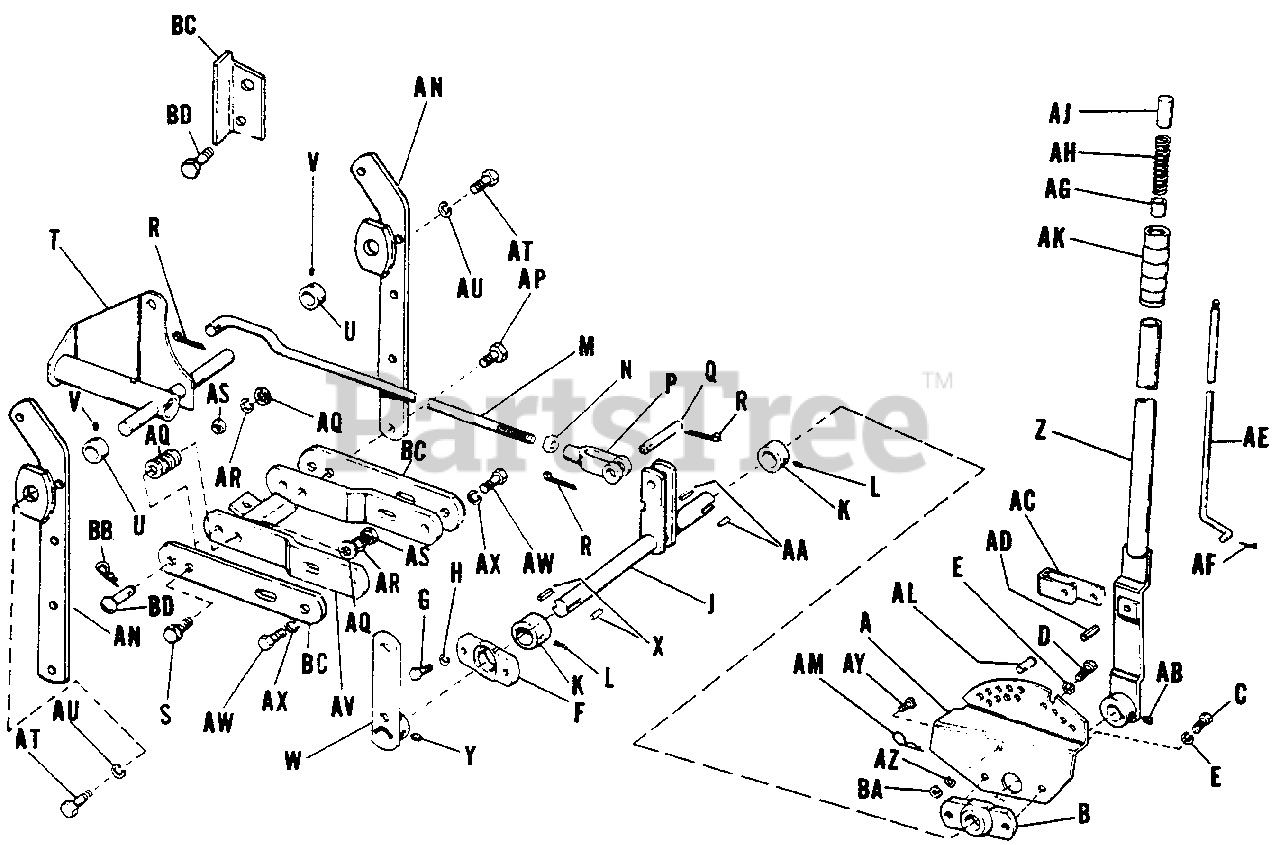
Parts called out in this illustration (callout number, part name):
A	Lift Lever Quadrant
B	Lift Lever Bearing (1542910)*
C	Hex. Cap Screw, 3/8"-16 x 7/8"
D	Hex. Cap Screw, 3/8"-16 x 1-1/4"
E	Lock Washer, 3/8"
F	Lift Lever Bearing (154210)*
G	Hex. Cap Screw 3/8"-16 x 7/8"
H	Lock Washer, 3/8"
J	Lift Shaft Assembly (157105)*
K	Set Collar (8211005)
L	Set Screw, 5/16"-18 x 5/16"
M	Rear Lift Rod
N	Full Hex Nut 1/2"-20
P	Adj-Yoke End (154304)*
R	Cotter Pin, 1/8" x 1"
S	Hex. Cap Screw, 7/16"-14 x 1 3/4"
T	Tiller Lift Assembly
U	Set Collar
V	Set Screw 5/16"-18 x 5/16"
W	Front Lift Lever Assembly
Y	Set Screw 5/16"-18 x 1/4"
Z	Lift Lever Assembly (157012)*
AA	Key (157120)*
AB	Set Screw 5/16"-18 x 1/4"
AC	Lift Lever Latch
AE	Latch Rod
AF	Cotter Pin, 3/32" x 3/4"
AJ	Thumb Button
AK	Handle Grip
AM	Spring Clip
AN	Arm Assembly (154200)*
AP	Hex. Capscrew, 7/16"-14 x 1-1/2"
AQ	Plain Washer, 3/8"
AR	Lock Washer, 7/16'
AS	Full Hex. Nut, 7/16"
AT	Hex. Cap Screw, 7/16"-14 x 1"
AU	Lock Washer, 7/16"
AV	Draw Bar Assembly
AW	Hex. Cap Screw, 7/16"-14 x 1-1/4"
AX	Lock Washer, 7/16"
AY	Screw 1/4-20 x 5/8" lg.
AZ	Lock Washer 1/4"
BA	Hex Nut Full 1/4-20
BB	Spring Clip
BD	Round Head Pin
BE	Seat Stop
BF	Hex, Capscrew, 5/16"-18 x 7/8"
